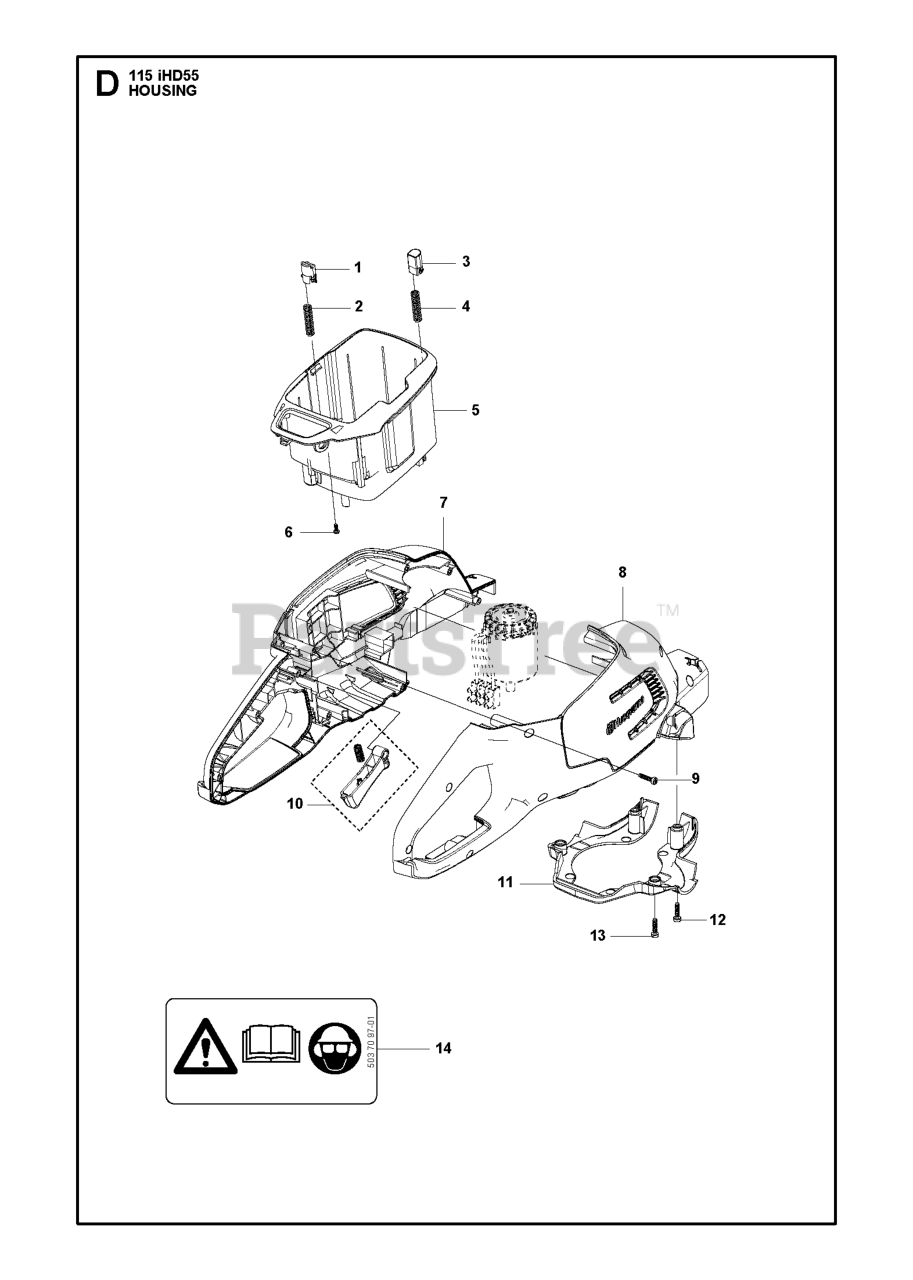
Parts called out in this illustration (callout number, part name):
1	PUSH BUTTON
2	SPRING PUSH BUTTON
3	PUSH BUTTON FRONT
4	SPRING PUSH BUTTON
5	BATTERY BOX
6	SCREW ST3X8
7	HOUSING LEFT - HOT FOIL+PAINTI
9	SCREW ST4X16
11	COVER BOTTOM
